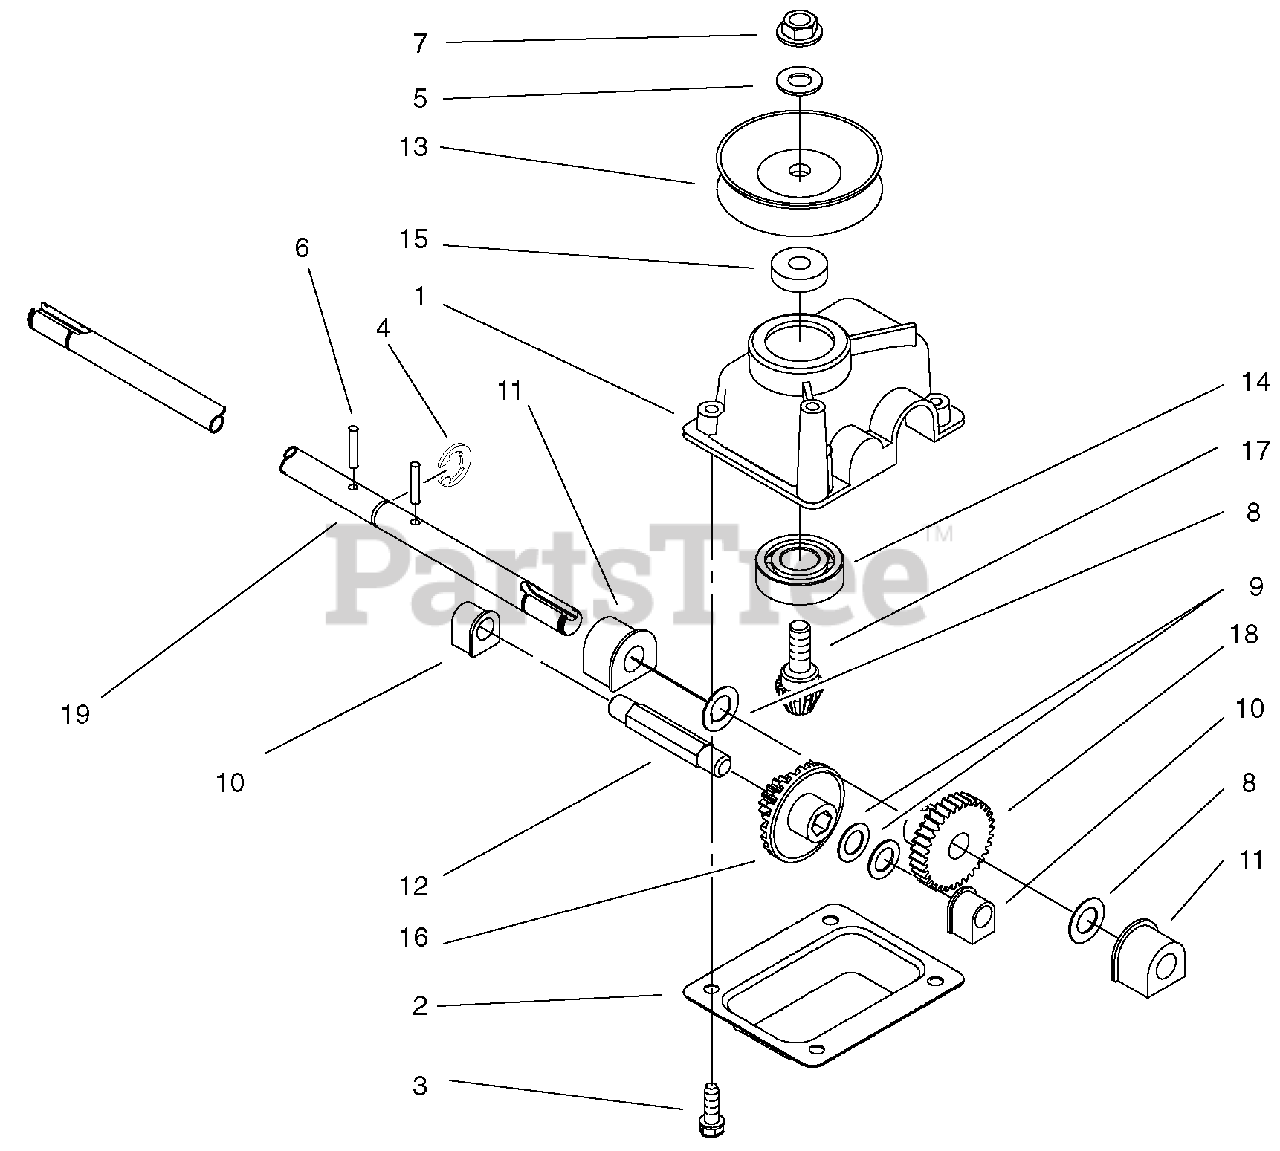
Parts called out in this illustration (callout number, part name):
1	CASE-GEAR
2	COVER-CASE, GEAR
3	SCREW-HWH
4	RING-RETAINING
5	WASHER-FLAT
6	PIN-GROOVE
7	NUT-LOCK, NI
9	WASHER-THRUST
11	BUSHING-OUTPUT
12	SHAFT-INTERMEDIATE
13	HALF-PULLEY
14	BEARING-BALL
16	GEAR-15T SPUR, 37T BEVEL
17	GEAR-PINION, BEVEL
19	SHAFT-OUTPUT
